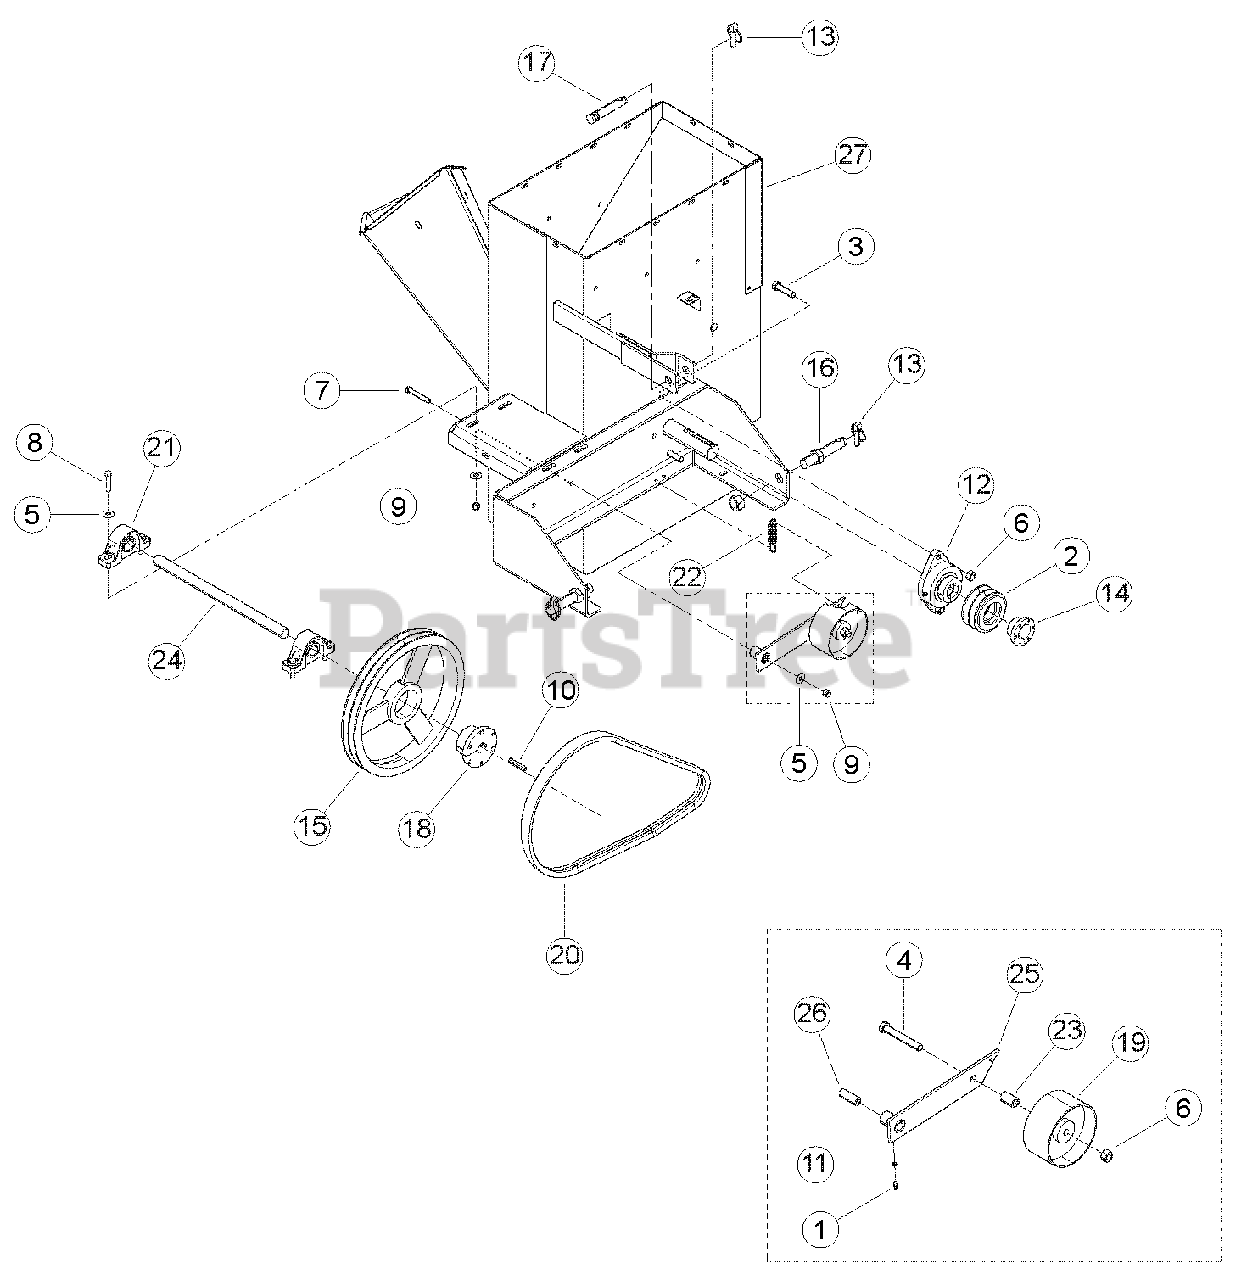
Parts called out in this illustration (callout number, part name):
1	FITTING, 1/4 SELF-TAP GREASE
2	SHEAVE, 2B3.4 SH,
3	BOLT, 1/2 X 2 HEX HD GR5 ZP
4	BOLT, 1/2 X 3-1/2 HEX HD GR5 ZP
5	WASHER, 3/8 FLAT ZP
6	NUT, 1/2 CENTERLOCK GRB ZP
7	BOLT, 3/8 X 2-1/2 HEX HD GR5 ZP
8	BOLT, 3/8 X 1-3/4 HEX HD GR5 ZP
9	NUT, 3/8 NE NYLOCK ZP
10	KEY, 1/4 SQUARE X 2 LONG PLAIN
11	WASHER, .254 X .400 X .048 FLAT
12	BEARING, 2 BOLT FLANGE 1-1/2" BORE
13	PIN, 7/16 X 1-3/4 LYNCH
14	BUSHING, SH 1-1/2"
15	SHEAVE, 2B13.6 SK
16	PIN, LIFT ARM 7/8 X 5 LONG
17	PIN, TOP LINK 3/4 X 4-1/2 LONG
18	BUSHING, 1" SK
19	PULLEY, IDLER 5" X 2.50"
20	BELT 2RB X 56
21	PILLOW BLOCK BEARING 1"
22	SPRING, 3/4"OD EXTENSION
23	SPACER, .75 X 1.18
24	JACKSHAFT, PTO C/S
25	WELDMENT, PTO IDLER ARM
26	SPACER .63 X 1.63
27	WELDMENT, PTO C/S FRAME
